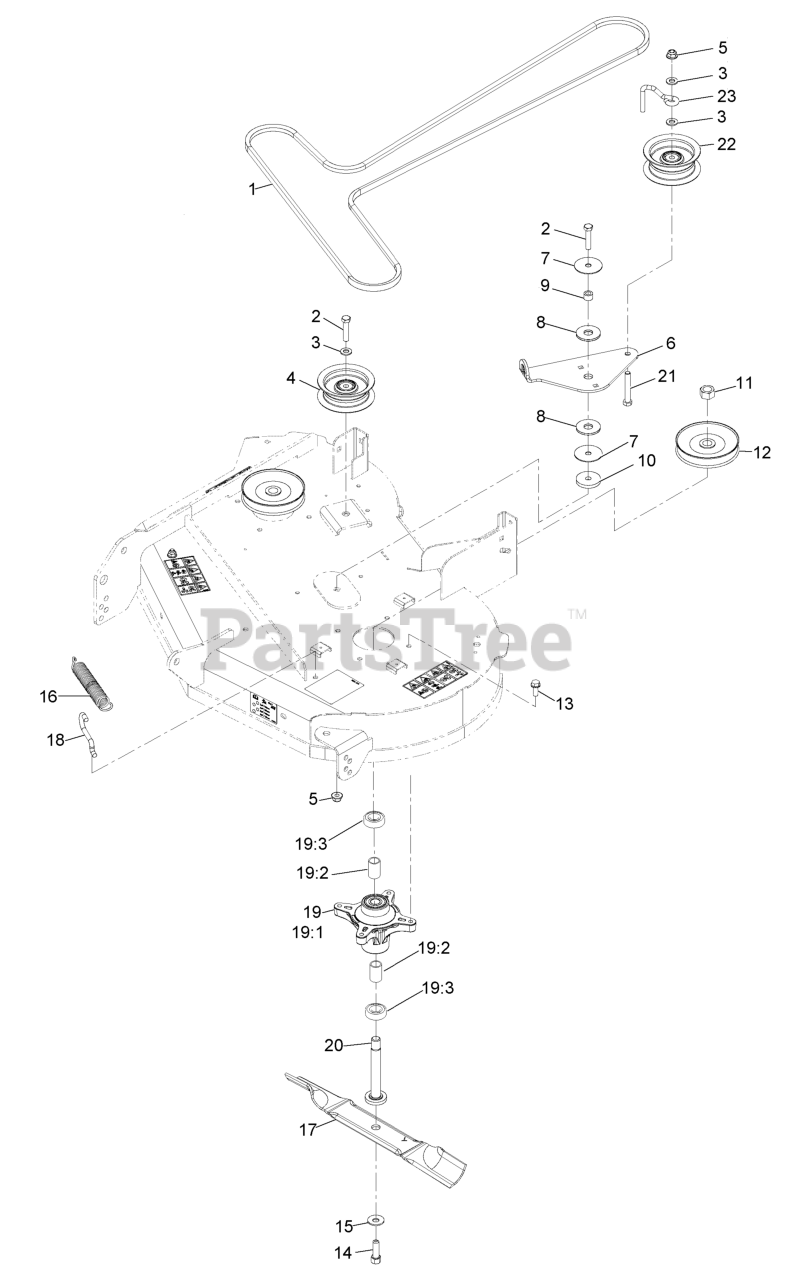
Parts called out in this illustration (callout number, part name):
1	BELT-V
2	SCREW-HH
3	WASHER-FLAT
5	NUT-HF, NI
6	ARM-IDLER
8	WASHER-FRICTION, COMPOSIT
10	WASHER-PLAIN
11	NUT-HEX
12	PULLEY ASM
13	SCREW-TAPTITE
14	SCREW-HH
15	WASHER-BELLEVILLE
16	SPRING-EXTENSION
17	BLADE-HI LIFT
18	HOOK-RETURN, SPRING
19	SPINDLE ASM
19:3	BEARING-BALL
20	SHAFT-SPINDLE
21	BOLT-CARR
23	GUIDE-IDLER, BELT
